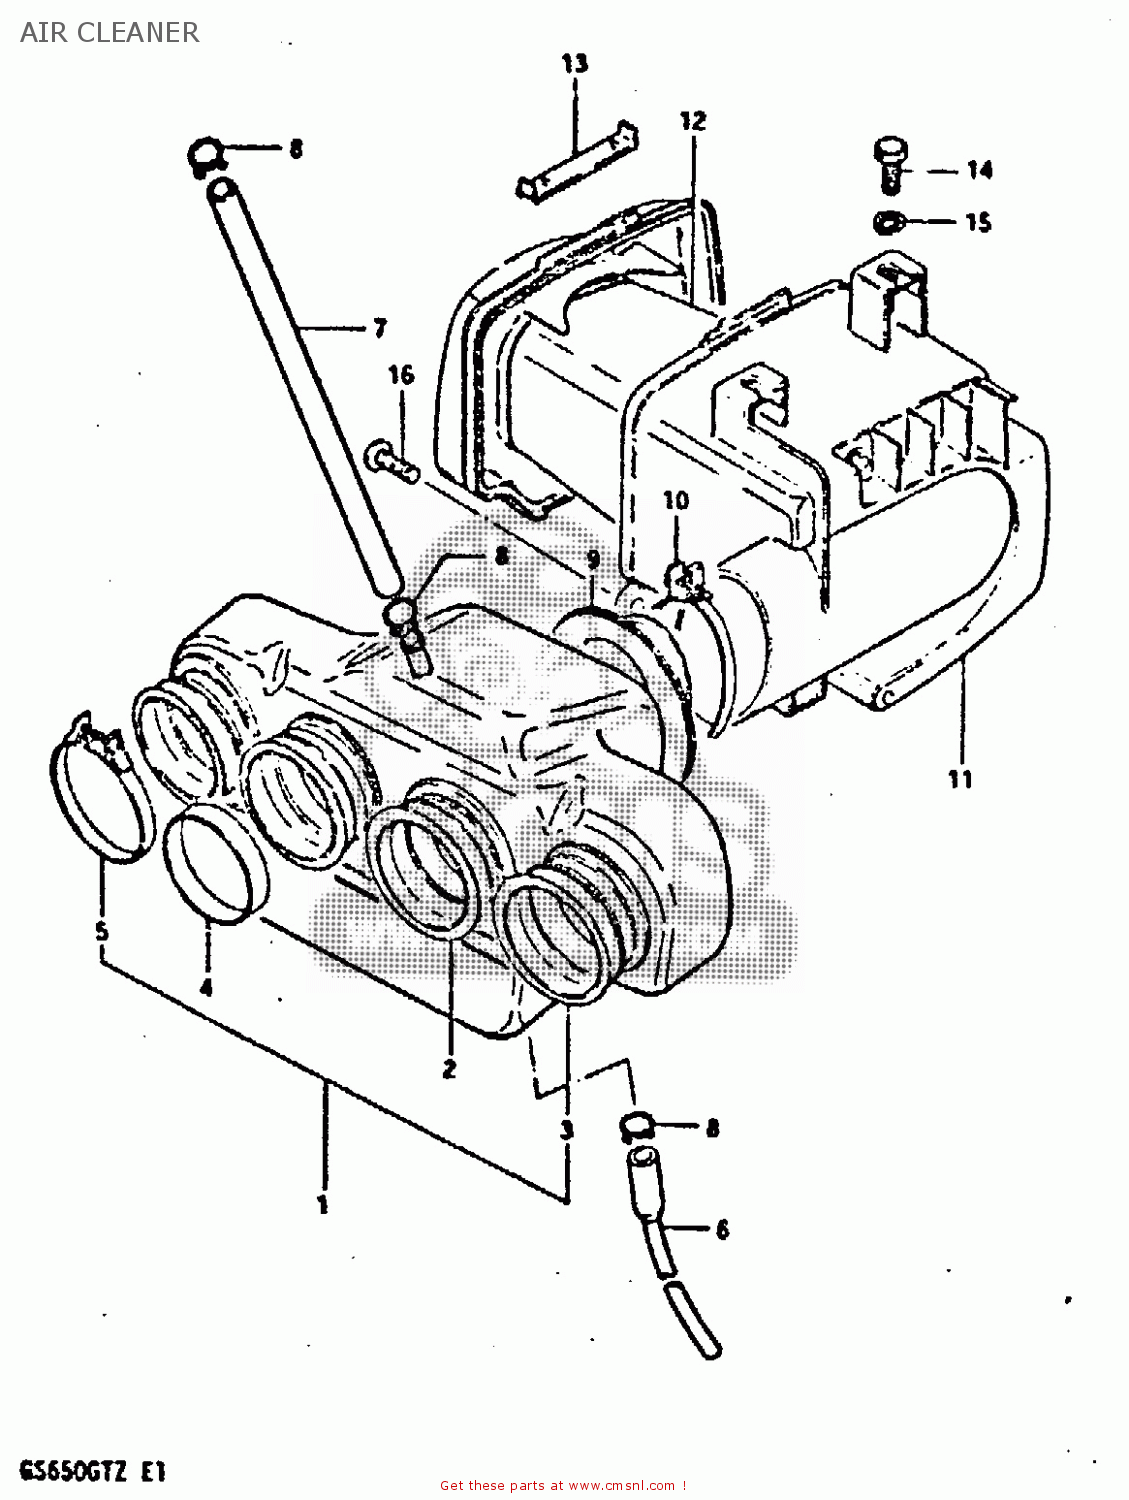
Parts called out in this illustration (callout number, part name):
1	CASE,AIR CLEANER,FRONT
2	TUBE,OUTLET,INNER
3	TUBE,OUTLET OUTER
4	RING,CARBURETOR AIR IN
5	CLAMP
6	DRAIN TUBE
7	HOSE
8	CLIP
9	JOINT,HOSE AIR CLEANER
10	CLAMP
11	CLEANER SET,AIR,REAR
12	FILTER ASSY
13	SLIDER
14	BOLT, UPPER
15	LOCK WASHER
16	SCREW
